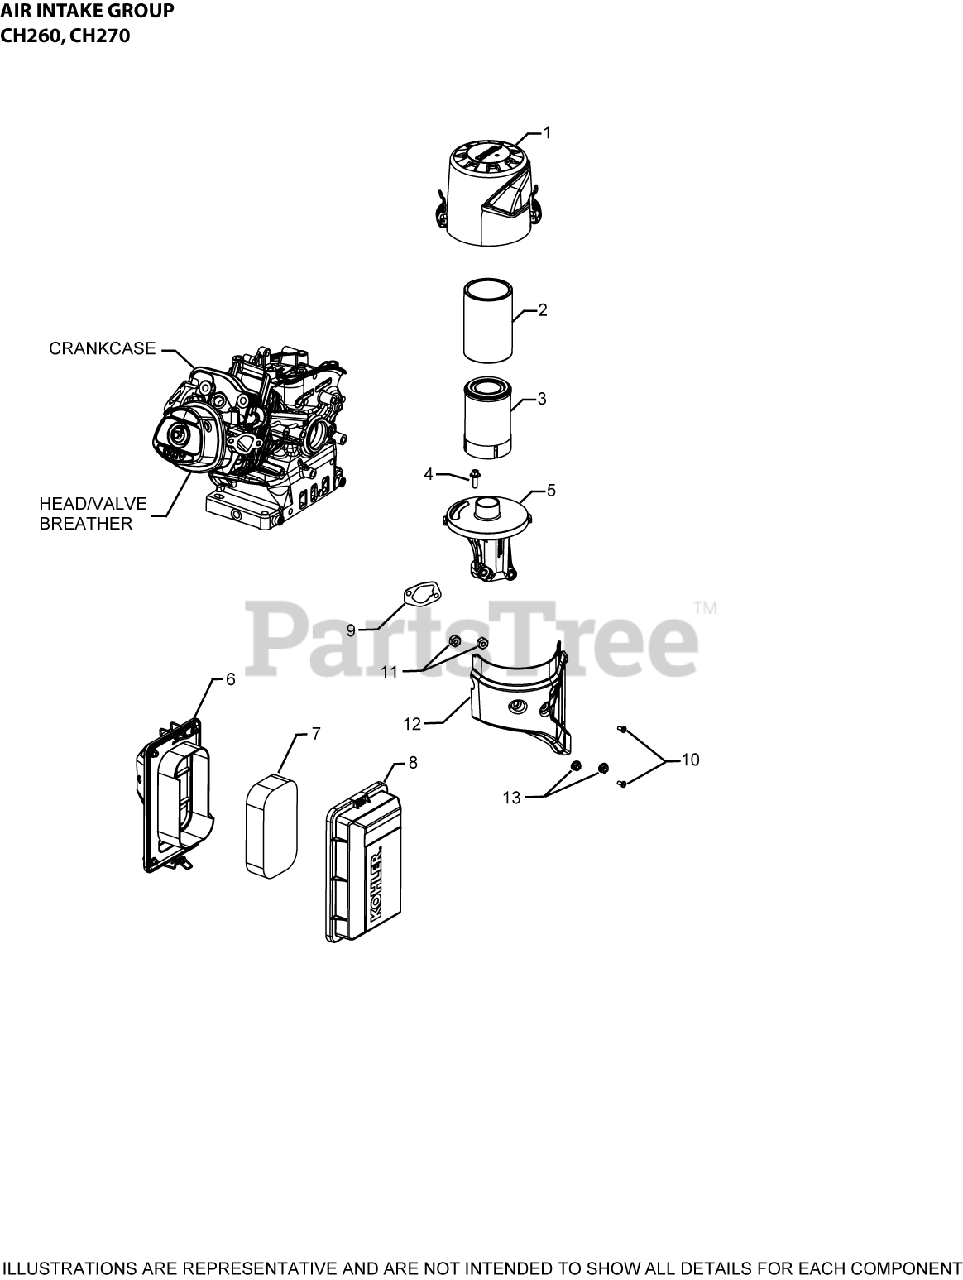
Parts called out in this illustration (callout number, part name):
1	COVER, AIR CLEANER ASSEMBLY
2	ELEMENT, PRE-CLEANER - USE 17 083 12-S
3	ELEMENT, AIR FILTER USE 17 083 23-S
4	SCREW, M6 X18
5	KIT, AIR CLEANER BASE ASSEMBLY
9	KIT, INTAKE GASKET
10	SCREW,COVR TO BLWR HOUSING
11	NUT, HEX (M6 THREAD, M8 BODY)
12	COVER, AIR CLEANER BASE SHIELD
13	NUT, HEX FLANGE LOCK (M6)
1734401-S	KIT, LATCH CLIP
